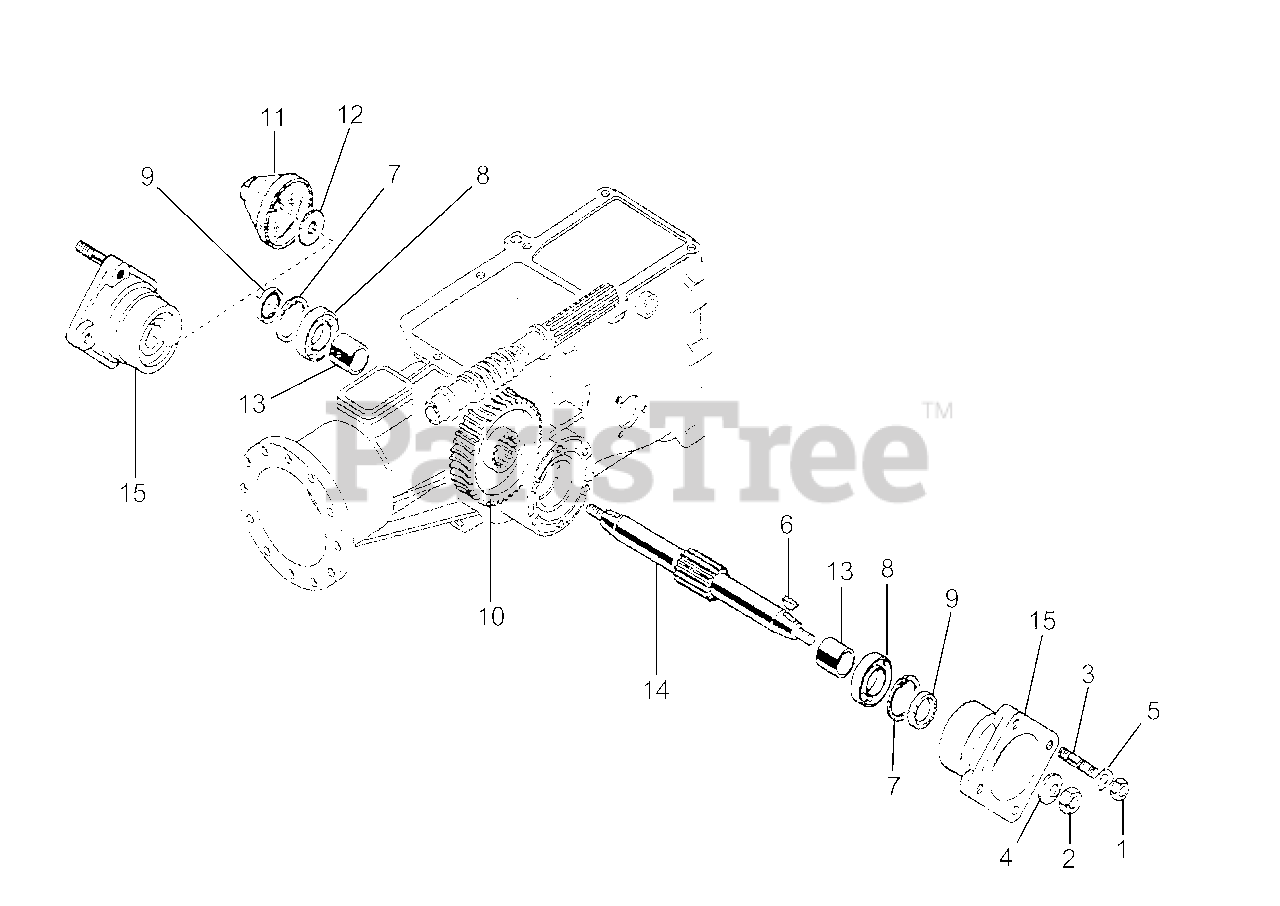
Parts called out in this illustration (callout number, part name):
1	NUT M 10 UNI 5588 6S
2	SELF-LOCKING NUT M12
3	STUD M10X40X22X14 8G
4	TOP WASHER 12
5	SPRING WASHER B10,5 DIN 137
6	KEY 6X10 UNI 6606
7	INSIDE SEEGER D 52 DIN 472
8	BEARING SKF 25X52X15 6205
9	OIL SEAL 25X52X10 NORMAL
10	CROWN GEAR Z=49 MF L-HAND 2
12	WASHER12.5X34X4
14	WHEEL SHAFT
15	WHEEL HUB WITH STUD
